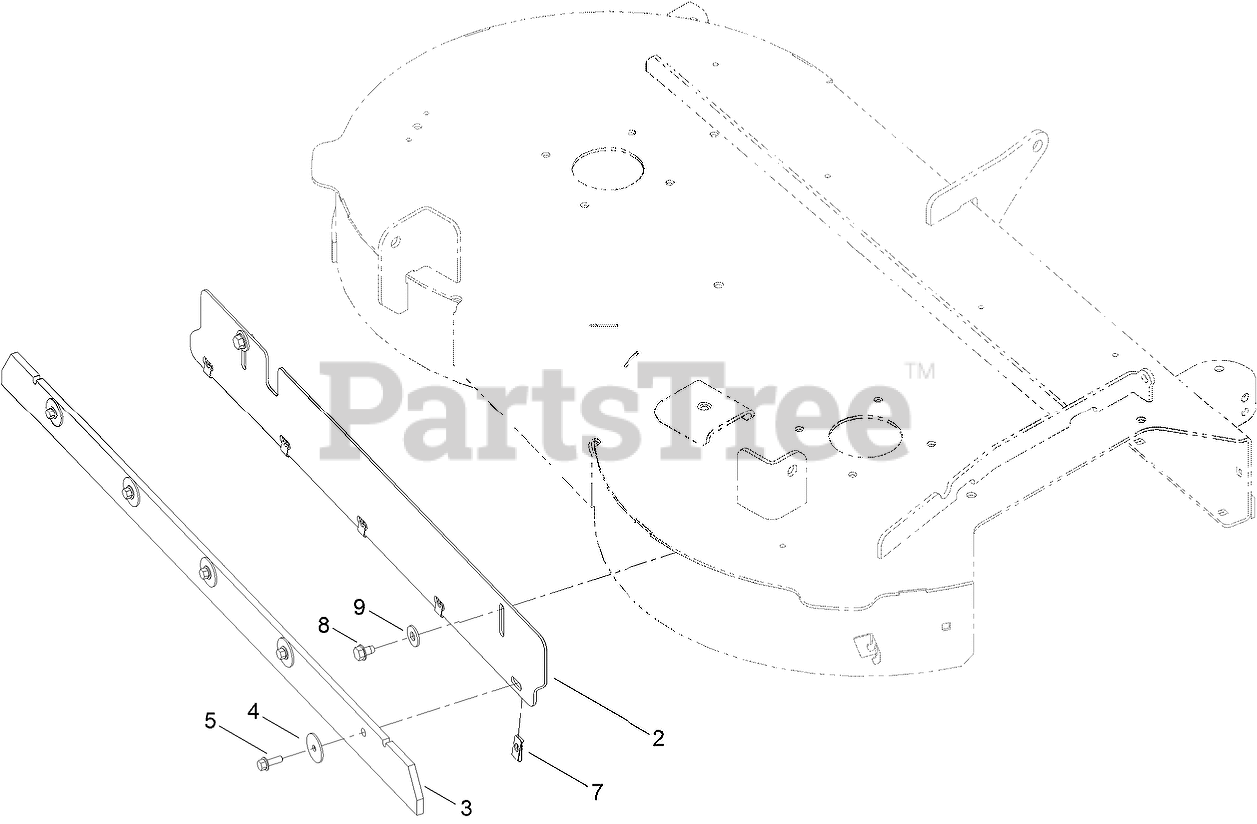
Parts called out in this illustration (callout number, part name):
2	BRACKET-STRIPING, 42
4	WASHER-FLAT
5	SCREW-HHF
7	NUT-SPEED
8	SCREW-HWH, THD ROLL
9	WASHER-FLAT
